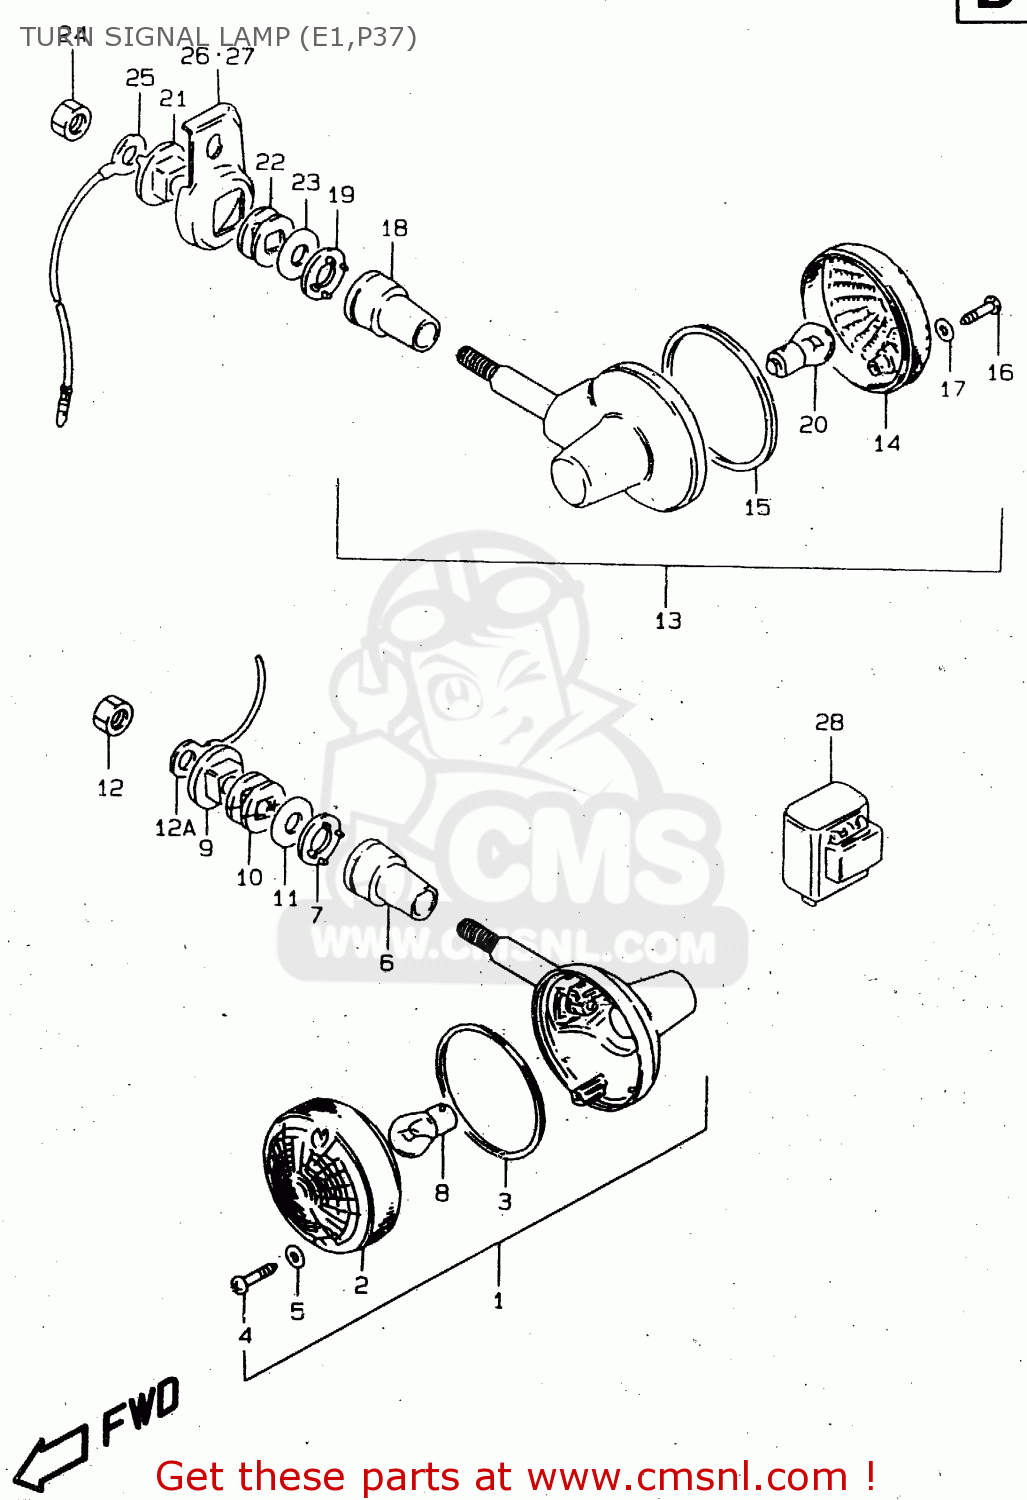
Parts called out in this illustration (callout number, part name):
1	LAMP ASSY,TURNSIGNAL
2	LENS
3	GASKET (NAS)
4	SCREW
5	GASKET (NAS)
6	COVER,STAY
7	CUSHION
8	BULB(12V23W,STANLEY,A4577A)
9	SPACER
10	CUSHION
11	WASHER(10.5X30X2.3)
12	NUT
12A	LEAD WIRE,EARTH
13	LAMP ASSY,TURNSIGNAL
14	LENS
15	GASKET (NAS)
16	SCREW
17	GASKET (NAS)
18	COVER,STAY
19	CUSHION
20	BULB(12V23W,STANLEY,A4577A)
21	SPACER
22	CUSHION
23	WASHER(10.5X30X2.3)
24	NUT
25	LEAD WIRE,EARTH
26	BRACKET,RR TURNSIGNAL LAMP,R
27	BRACKET,RR TURNSIGNAL LAMP,L
28	RELAY ASSY,TURNSIGNAL
